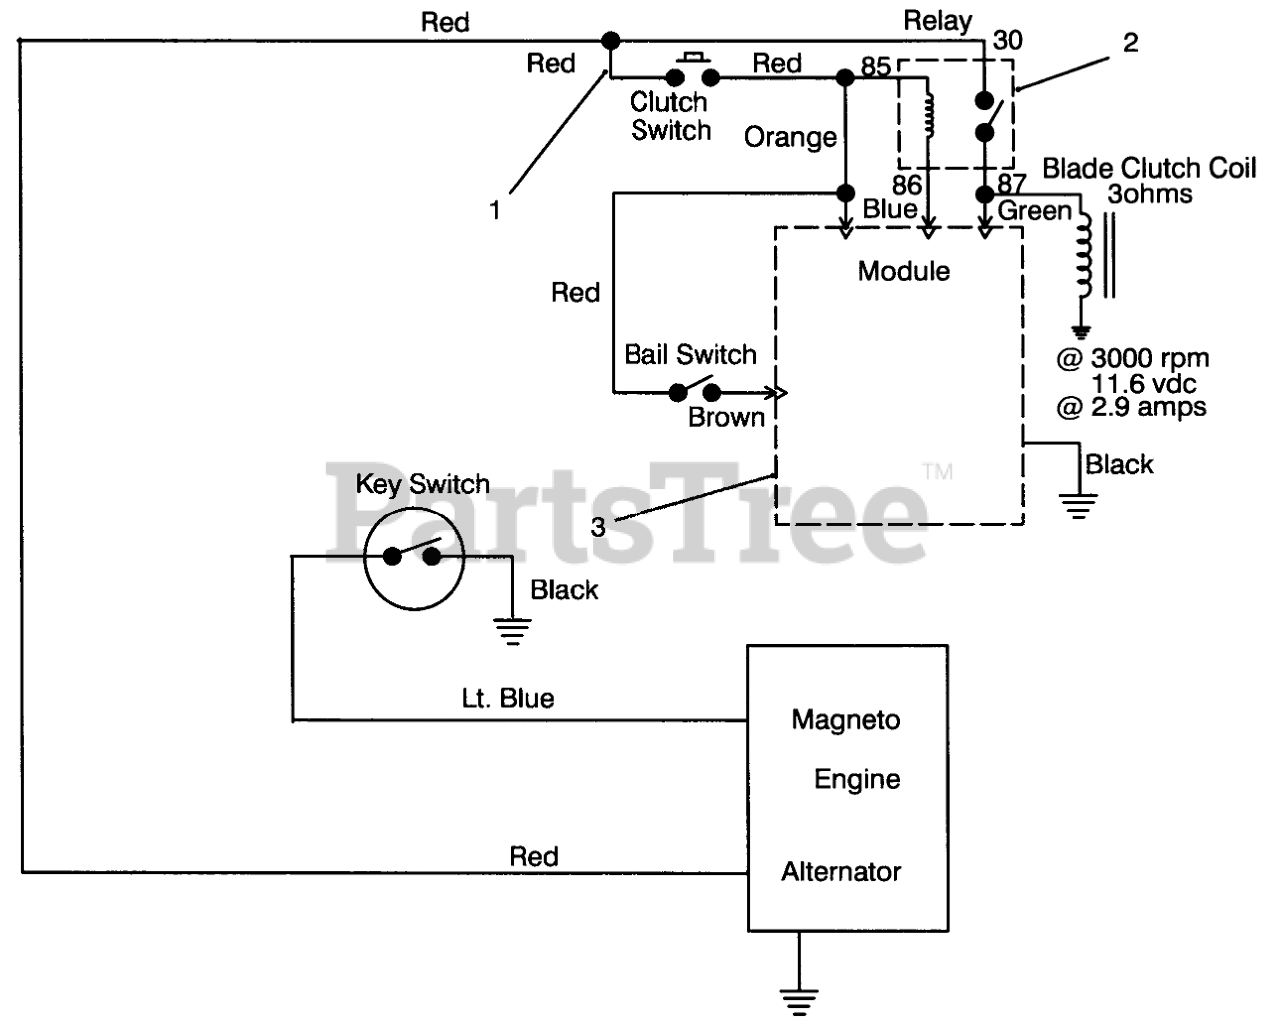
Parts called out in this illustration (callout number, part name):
1	WIRE HARNESS
2	RELAY
3	Module
